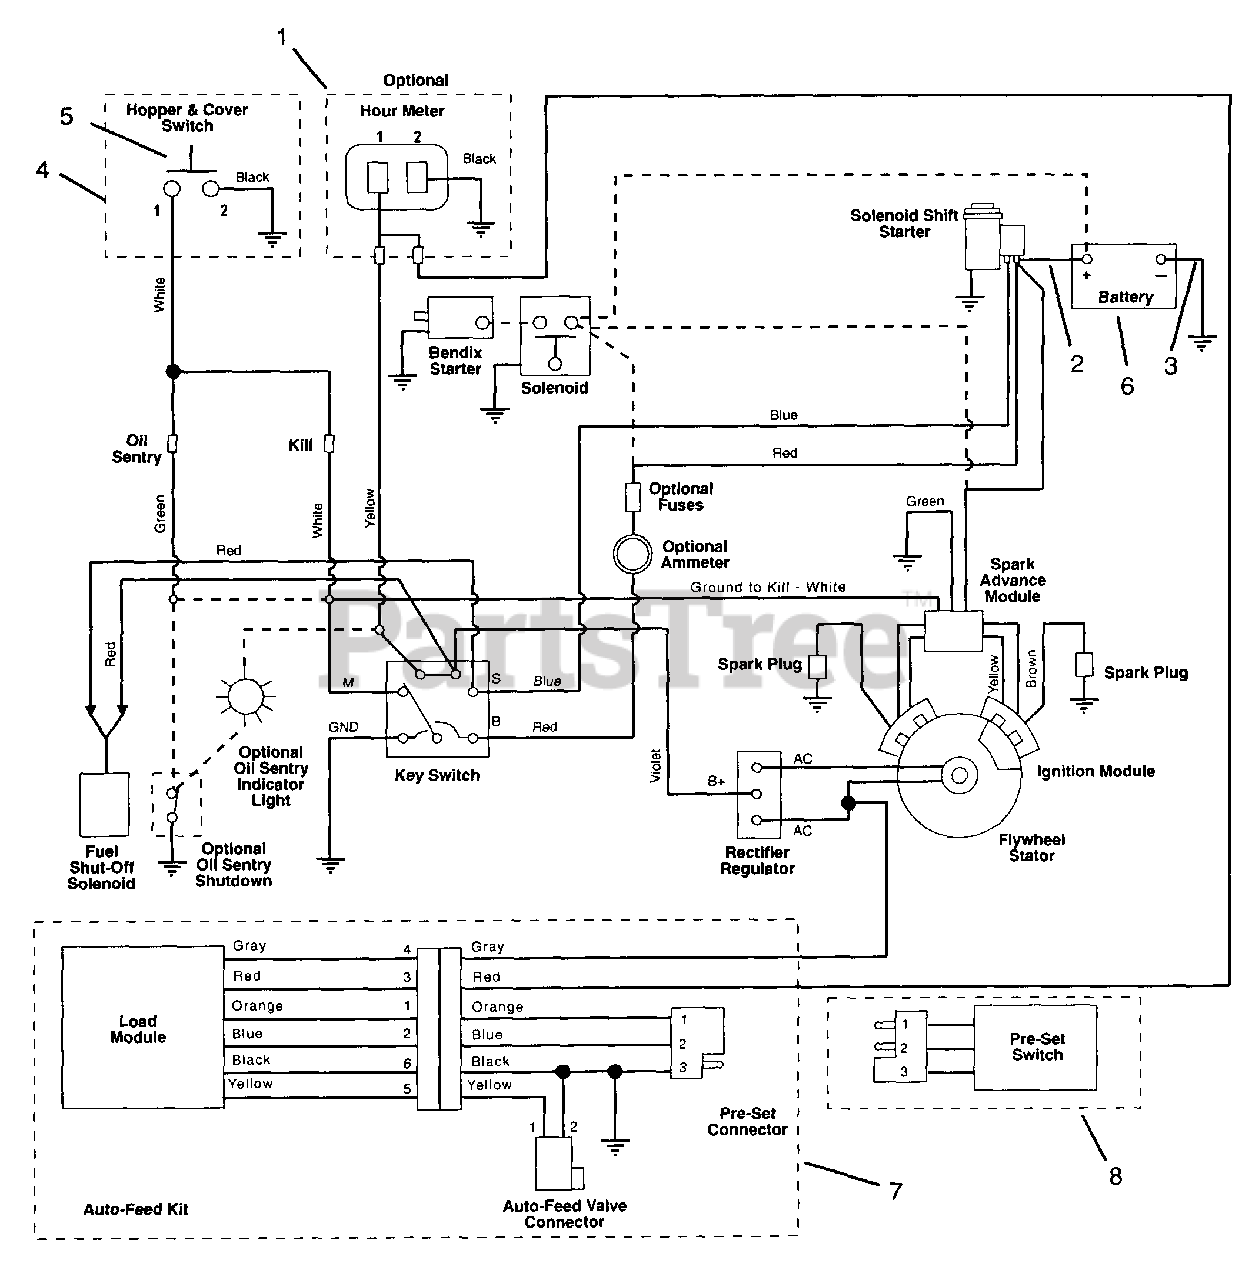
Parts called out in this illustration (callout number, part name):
1	Accessory-Hour Meter
2	Battery Cable (Positive)
3	Battery Cable (Negative)
4	Harness-Wiring
5	Switch-Safety
7	Auto-Feed Conversion 625LR
8	Pre-Set Switch
